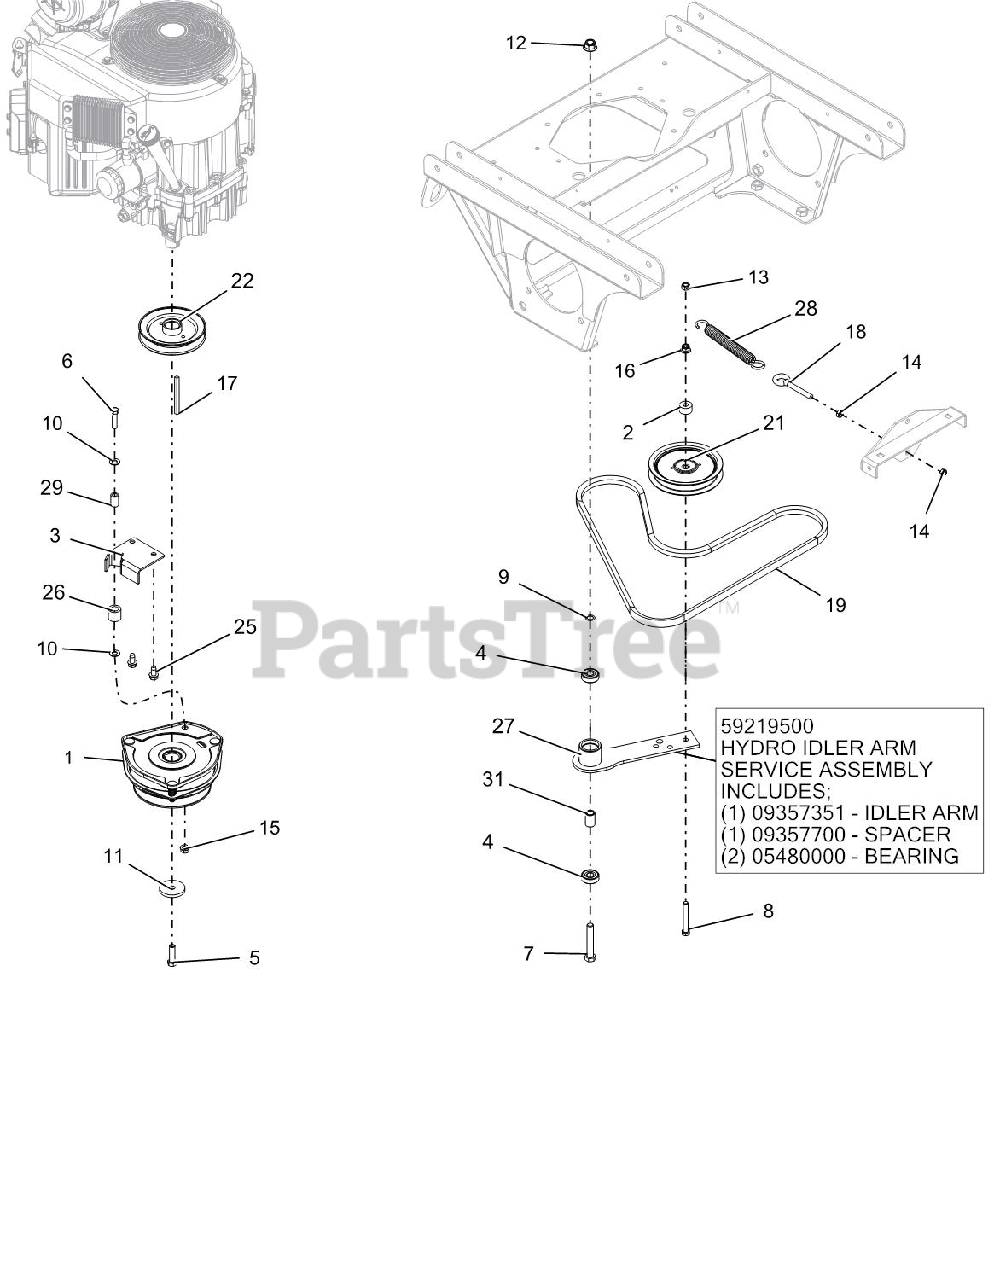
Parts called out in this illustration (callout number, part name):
1	CLUTCH-OGURA
2	SPACER .390X1.000X.562
3	WLDMT, CLUTCH STOP (BLACK)
4	BRG-BALL .500X1.375X.44
5	BLT-HEX .44-20X1.50 GR5 YWZC
6	BLT-HEX .38-16X1.50 GR5 YWZC
7	BLT-HEX .50-13X3.00 GR5 YWZC
8	BLT-HEX .38-16X2.75 GR5 YWZC
9	WASHER-FLAT-STL, .500 X .750 X .020
10	WSHR-FL-STL.406X.812X.065 YWZ
11	WSHR-FL-STL .469X2.00X.25 YWZC
12	NUT-LK-NYL-FLG .50-13 YWZC
13	NUT-LK-CTR .38-16 YWZC
14	NUT, JAM .375-16 YWZC
15	NUT, LK-TOP-FLG .38-16 YWZC
16	NUT-LK-NYL-FLG .38-16 YWZC
17	KEY-SQ .250X.250X3.50
18	BOLT, EYE .375-16
19	BELT, B RAW COGGED
21	IDLER, FLAT - 5.00" X .75"
22	SHEAVE, ENGINE 1.127 ID X 5.250 OD-BLACK
25	SCR-TAP .38-16X.75 HWH TR YWZ
26	BUMPER, RUBBER .62 X 1.0 X .88 LG
27	HYDRO IDLER ARM SERVICE ASSEMBLY
27	IDLER ARM
27	SPACER
27	BEARING
27	WLDMT, HYDRO DRIVE IDLER ARM-BLACK
28	SPRG, EXTENSION - SWIVEL
29	BUSH.,S.391X.622X.95 ST REV A
31	SPACER, .510 X .750 X 1.148
